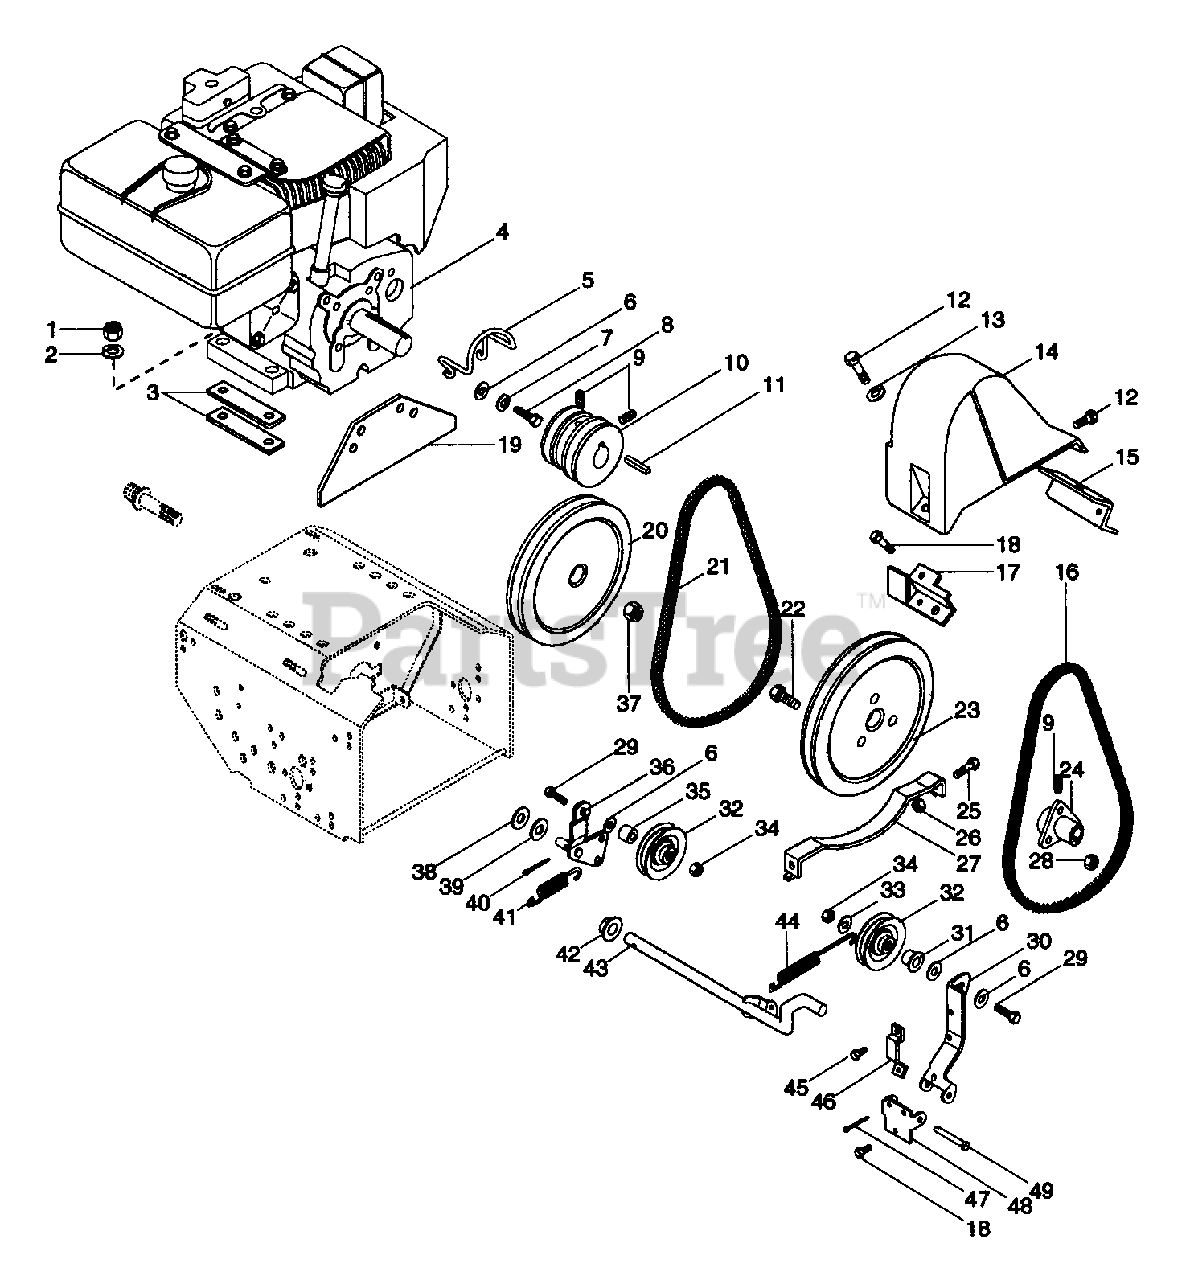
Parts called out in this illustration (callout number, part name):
1	NUT-HEX .312-18
2	WSHR-LK .312X.097 PL HVY
3	STRAP
4	8HP TEC ENGINE
5	BELT FINGER
6	WSHR-FL-STL .38X.875X.083 PL
7	WSHR-LK-EXT .313X.030 PL
8	BLT-HEX .31-24X.75 PL GR5
9	SCR-SET .32-18X.38 SKHCUPNL OH
10	ENGINE SHEAVE
11	KEY-STR .25X1.75X.25
12	SCR-TAP .25-20X.50 HWHPL
13	WSHR-FL-STL .268X.562X.046 PL
14	BELT COVER
15	L.H. SUPPORT
16	V-BELT, 4L-RAW EDGE
17	R.H. SUPPORT
18	SCR-TAP .250-20X.37 HWH PL TR
19	PLATE
20	PLY-V 8.00 X 1.0 W/KEY CLARK
21	V-BELT, 3L-RAW EDGE
22	BLT-SERRDHD SL .31-18X.87 PL
23	PLY-V 9.0 X 1.25 3BLT
25	BLT-HEX .25-20X.50 PL GR2
26	NUT-LK-CTR .250-20 PL
27	BELT RETAINER
28	NUT-FLG. .312-18 PL
29	BLT-HEX .31-18X1.25 PL GR2
30	ARM, IDLER
31	SPCR, BRG .315X.50X.688X.281
32	IDLER
33	WSHR-FL-STL.312X.734X.065PL
34	NUT-LK .312-18 GR A PL
35	SPACER .50 X .32 X .42
36	IDLER ARM
37	NUT-LK-NYL.625-18 PL
38	WAVE WASHER .406X.750X.063FH
39	WSHR-FL-STL .382X.812X.023 PL
40	PIN-COTR .12X1.0 PL
41	SG-TENS .080X.73X3.06 WLD 20
42	BSHG-FLG.500X.625X.312X.750NY
43	ACTIVATING SHAFT
44	SG-TENS .047X.44X3.37 WLD 1.47
45	SCR-TAP 10-24X.375 HWH PL TR
46	RETURN CLIP
47	PIN-COTR .09X.75 PL
48	BRACKET
49	PIN-CLEV .309X2.25
